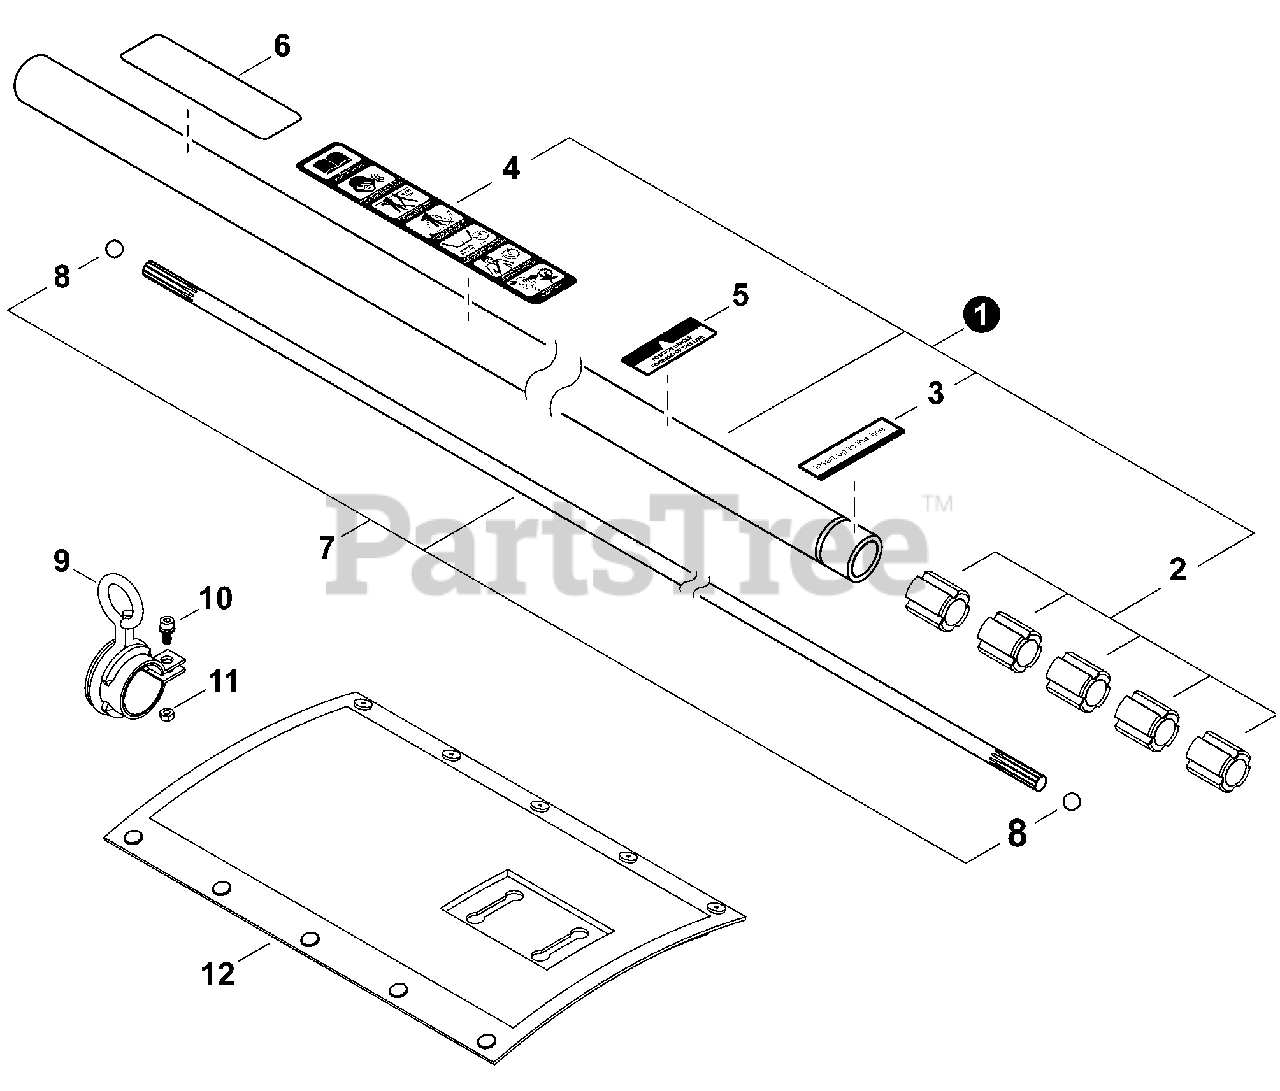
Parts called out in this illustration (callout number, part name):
1	MAIN PIPE ASSY
2	BUSHING
3	LABEL - ALIGNMENT
4	LABEL, CAUTION (BLADE CAPABLE)
5	LABEL, HANDLE
6	LABEL, SHINDAIWA PROFESSIONAL
7	SHAFT ASSY, DRIVE
8	STOPPER
9	HANGER
10	BOLT M5×12
11	NUT M5
12	PROTECTOR
